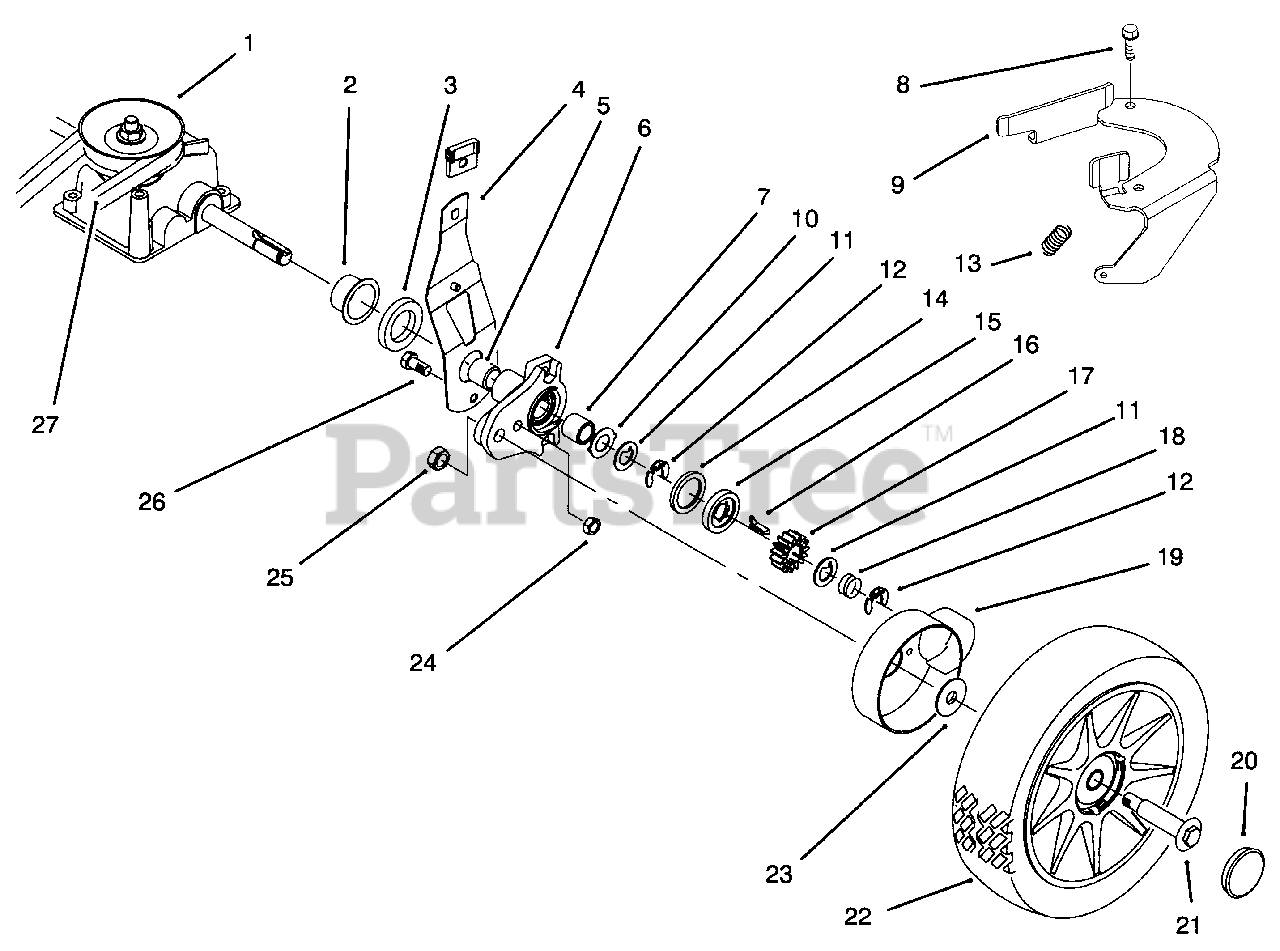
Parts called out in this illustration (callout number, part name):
1	Gear Case Assembly
2	Ring-Isolator
3	Spacer-Axle Shaft
4	Knob & Spring Assembly
6	Arm-Height Adjustment
8	Screw-Hex Hd. Cap
9	Guide-Belt
10	Washer-Thrust
11	Washer-Thrust Keyed
12	Ring-Retaining
13	Spring-Extension
14	Ring-Friction
16	Key-Rocking L.H.
17	Gear-Pinion
18	Spring-Compression
19	Cover-Wheel
21	Bolt-Shoulder
22	Wheel & Tire Assembly 8"
23	Washer-Stepped
24	Nut-Lock
25	Nut-Lock
26	Screw-Tapping
